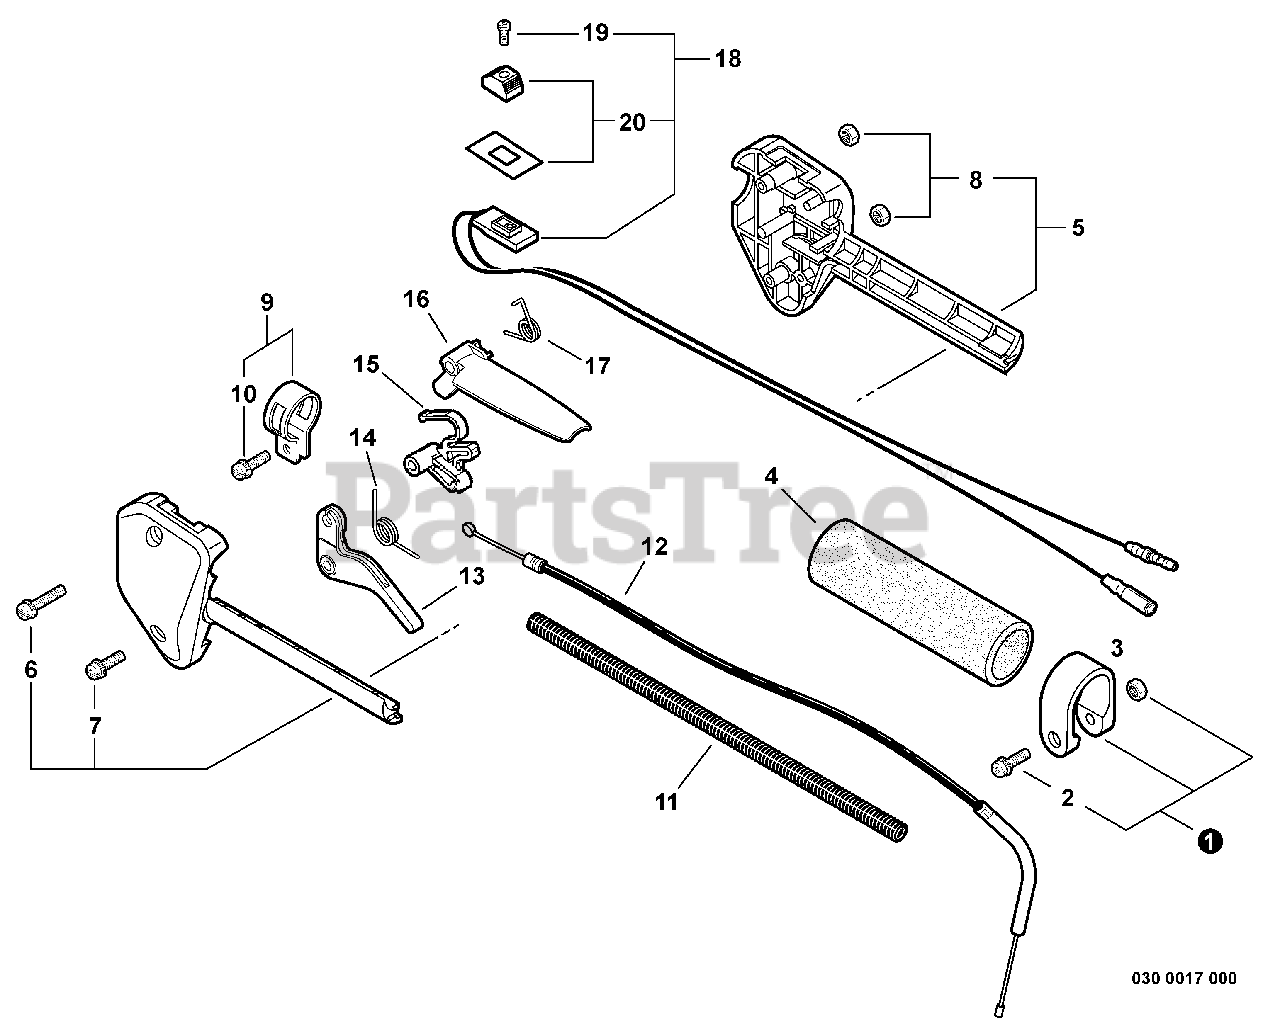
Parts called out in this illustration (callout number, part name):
1	CLAMP KIT
2	SCREW 5×28
3	NUT M5
4	GRIP, HANDLE
5	HANDLE KIT, CONTROL
6	SCREW 5×35
7	SCREW 5×25
8	NUT M5
9	CLAMP KIT
10	SCREW 5×14
11	TUBE, FLEXIBLE
12	CABLE, THROTTLE
13	TRIGGER, THROTTLE
14	SPRING, TORSION
15	LOCKOUT, THROTTLE
16	LEVER, THROTTLE LOCKOUT
17	SPRING, TORSION
18	SWITCH, ON-OFF
19	SCREW 3×10
20	KNOB, SWITCH - ORANGE
